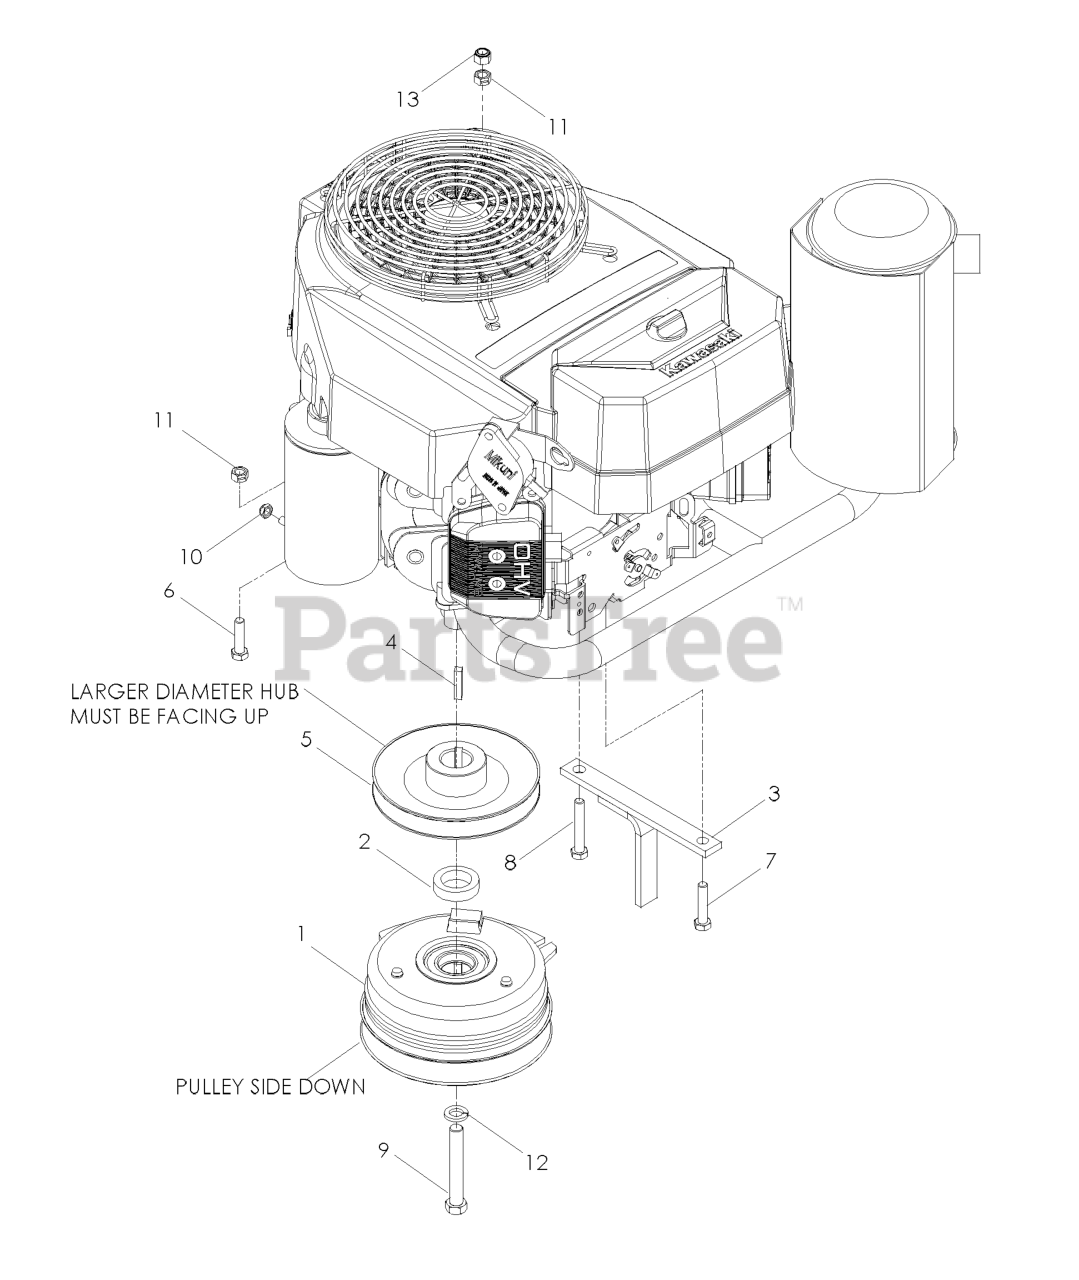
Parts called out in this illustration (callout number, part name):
1	CLUTCH 125 FT/LB
3	CLUTCH TIE DOWN
4	KEY 1/4 SQ X 1 1/8
6	HCS 5/16C X 1 1/4
7	CAPSCREW 5/16 X 1/1/2 HEX HEAD
8	HCS 5/16-18X2
9	HEX SCREW 7/16-20 X 3
10	JAM NUT 1/4C (2 2 PW01)
11	NUT 5/16C CENTERLOCK
12	WASHER 7/16 LOCK
13	NUT 5/16 NYLOC
